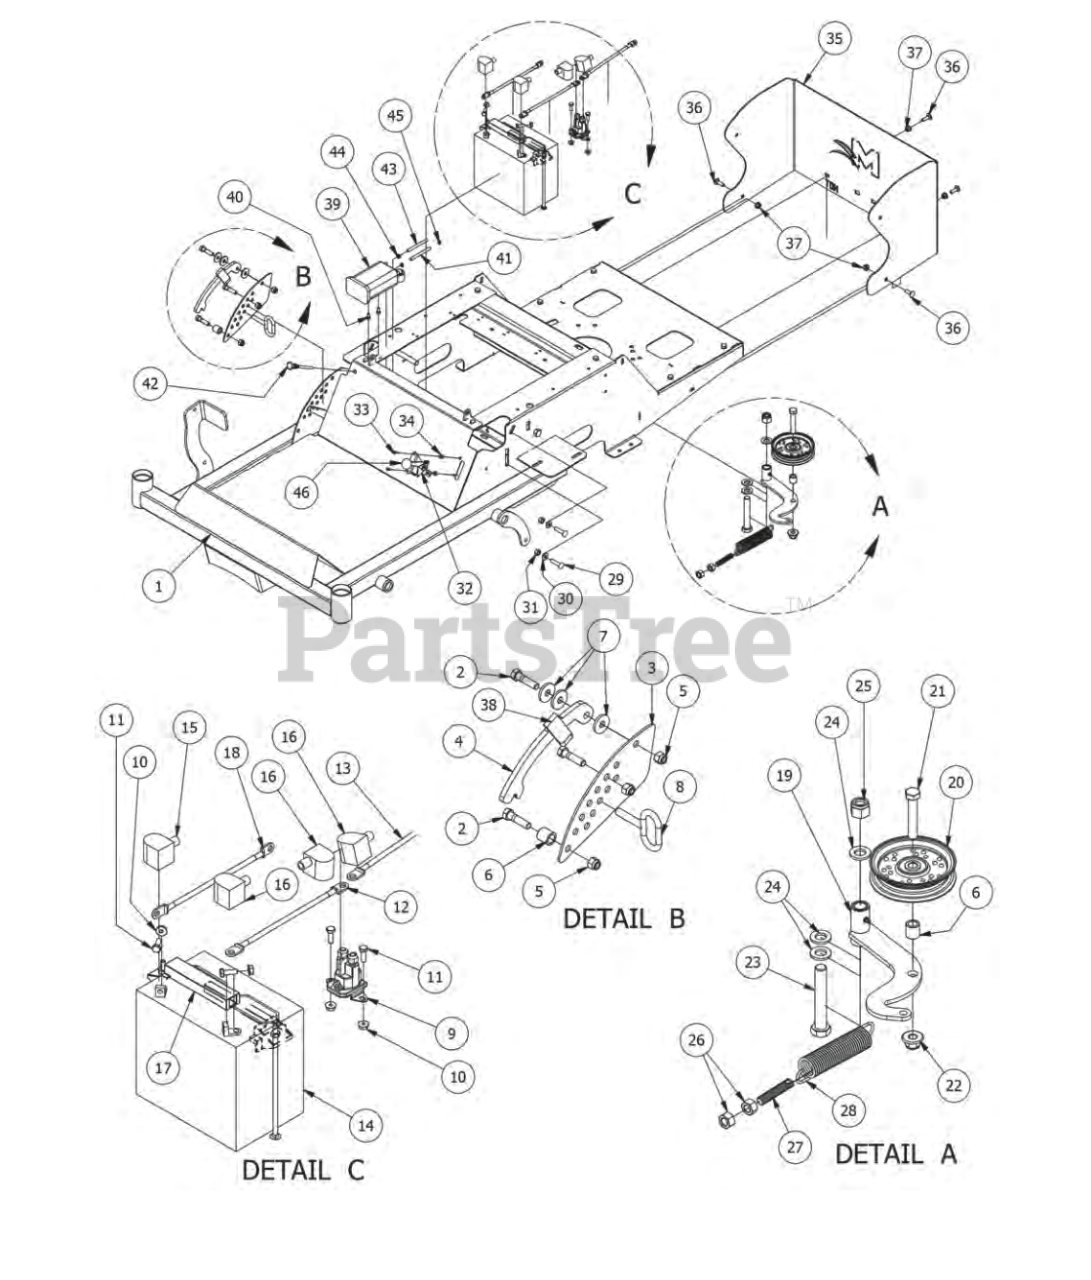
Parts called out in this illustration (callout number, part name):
2	3/8" x 1 1/2" Hex Bolt
3	MZ Height Indicator Plate
4	MZ Deck Level Lock Lever
5	3/8 Nylock Nut
6	3/4 OD x 1/2 ID x 3\4 Length
7	.390 ID Plastic Washer
8	Deck height lever pin
10	1/4-20 Hex Flange Nuts Zinc w/Serrations
11	1/4-20 x 3/4 GR 5 Hex Bolts Zinc
12	10" red battery cable
13	62" red cable
15	Black Boot For ground cable
17	Battery Hold Down
18	24" Ground Cable
19	MZ Idler arm Bracket
20	43/4 Idler Pulley - ABFI-76
21	1/2" x 2 3/4" Hex Bolt
22	1/2-13 Nylon Flange Nut-Orange
23	5/8" x 4" Hex Bolt
24	.635 ID Plastic Washer
25	5/8 Std NC Nylock Nut
26	1/2" Hex Nut
27	All Thread-pump Idler Tensioner
28	Deck spring big diameter
29	3/8-16 x 1-1/2 short neck bolt
30	3/8" Flat Washer
31	3/8" Hex Nut
32	Brake cable for MZ
33	10-24 X 5/8 BS C/S 18-8 SS
34	10-24 Nylon Insert Locknut
35	MZ Back Plate
36	5/16" x 1" Carriage Bolt
37	5/16" Flange Nut Zinc W/Serrations
38	Deck Height Handle Grip MZ
39	Carbon Canister for Magnum/MZ
40	M6-1.0 X 12MM Bolt 8.8
41	3/16 vinyl tubing
42	Choke Kohler engine
43	1/4" vinyl tubing
44	1/4" vinyl clamp
45	3/16" Vinyl Hose Clamp
46	Universal Throttle Head
